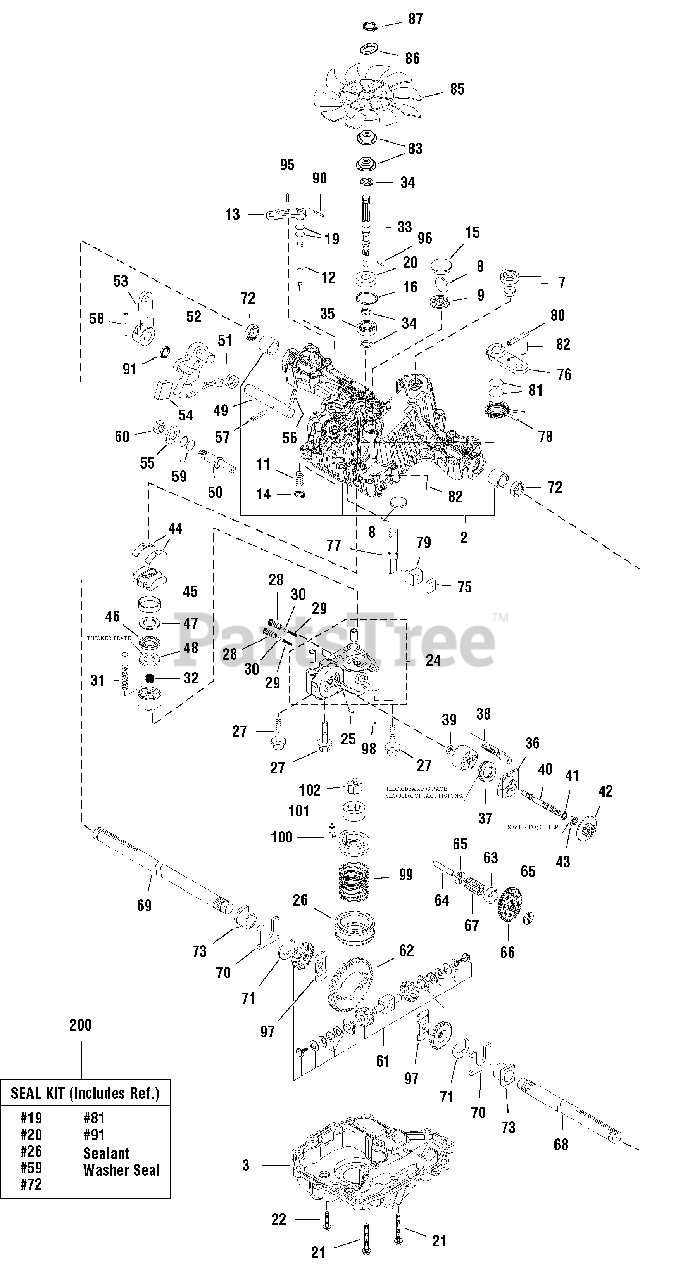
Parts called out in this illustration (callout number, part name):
2	HOUSING ASSEMBLY, UPPER
3	HOUSING, LOWER
7	VENT VALVE 15
8	MAGNET, K50
9	HOLDER, MAGNET
11	SPRING
12	SHAFT, BYPASS
13	LEVER, BYPASS
15	SEALING CAP
16	RING 35
19	PACKING
20	SEAL TC
21	SCREW, TAPPING
22	SCREW, TAPPING
24	CASE, CENTER
25	PIN 3 x 9.8
26	FILTER
27	BOLT 10 x 75
28	VALVE, IDS 1.0
29	SPRING, IDS
30	BALL, 3/16
31	CYLINDER BLOCK ASSEMBLY
32	SPRING, PUMP
33	SHAFT, PUMP
34	RING E15
35	BEARING
36	HOUSING
37	BEARING, THRUST
38	BLOCK, CYLINDER
39	WASHER 12 x 24 x 1
40	SHAFT, MOTOR
41	RING 15
42	GEAR, MOTOR
43	BEARING 6202UC3
44	THRUST METAL
45	SWASH PLATE ASSEMBLY
46	THRUST PLATE B
47	BEARING K81105
48	THRUST PLATE A
49	SHAFT, CONTROL
50	FULCRUM, ECCENTRIC
51	SPRING, TORSION
52	LEVER, CONTROL
53	ARM, CONTROL
54	PLATE, JERK
55	WASHER
56	PIN, COTTER
57	PIN, SPRING
58	PIN 6.0A x 4.0
59	PACKING
60	NUT 12
61	GEAR & PINION ASSEMBLY
62	GEAR, FINAL CONTR TRAC
63	COLLAR, PINION
64	SHAFT, REDUCTION
65	WASHER, 12 x 32 x 3.2
66	GEAR, REDUCTION
67	PINION, FINAL
68	SHAFT, AXLE RH
69	SHAFT, AXLE LH
70	WASHER, THRUST
71	RING 17
72	SEAL 19 x 32 x 8
73	BUSHING 19 x 21
75	SHOE, BRAKE
76	ARM, BRAKE
77	SHAFT, BRAKE
78	SPRING, RETURN B
79	BRAKE, ACTUATOR
80	PIN
81	PACKING
82	PIN, SPRING
83	COLLAR, SPLINE
85	FAN
86	LOCKWASHER
87	RING, SNAP
90	PIN 3.0A x 20
91	OIL SEAL
95	PIN, ROLL
97	WASHER, THRUST DIFF
98	PIN, 3.0A x 18
99	SPRING, CHARGE
100	CHARGE PUMP CASE ASSEMBLY
200	K57 SMP SEAL KIT
